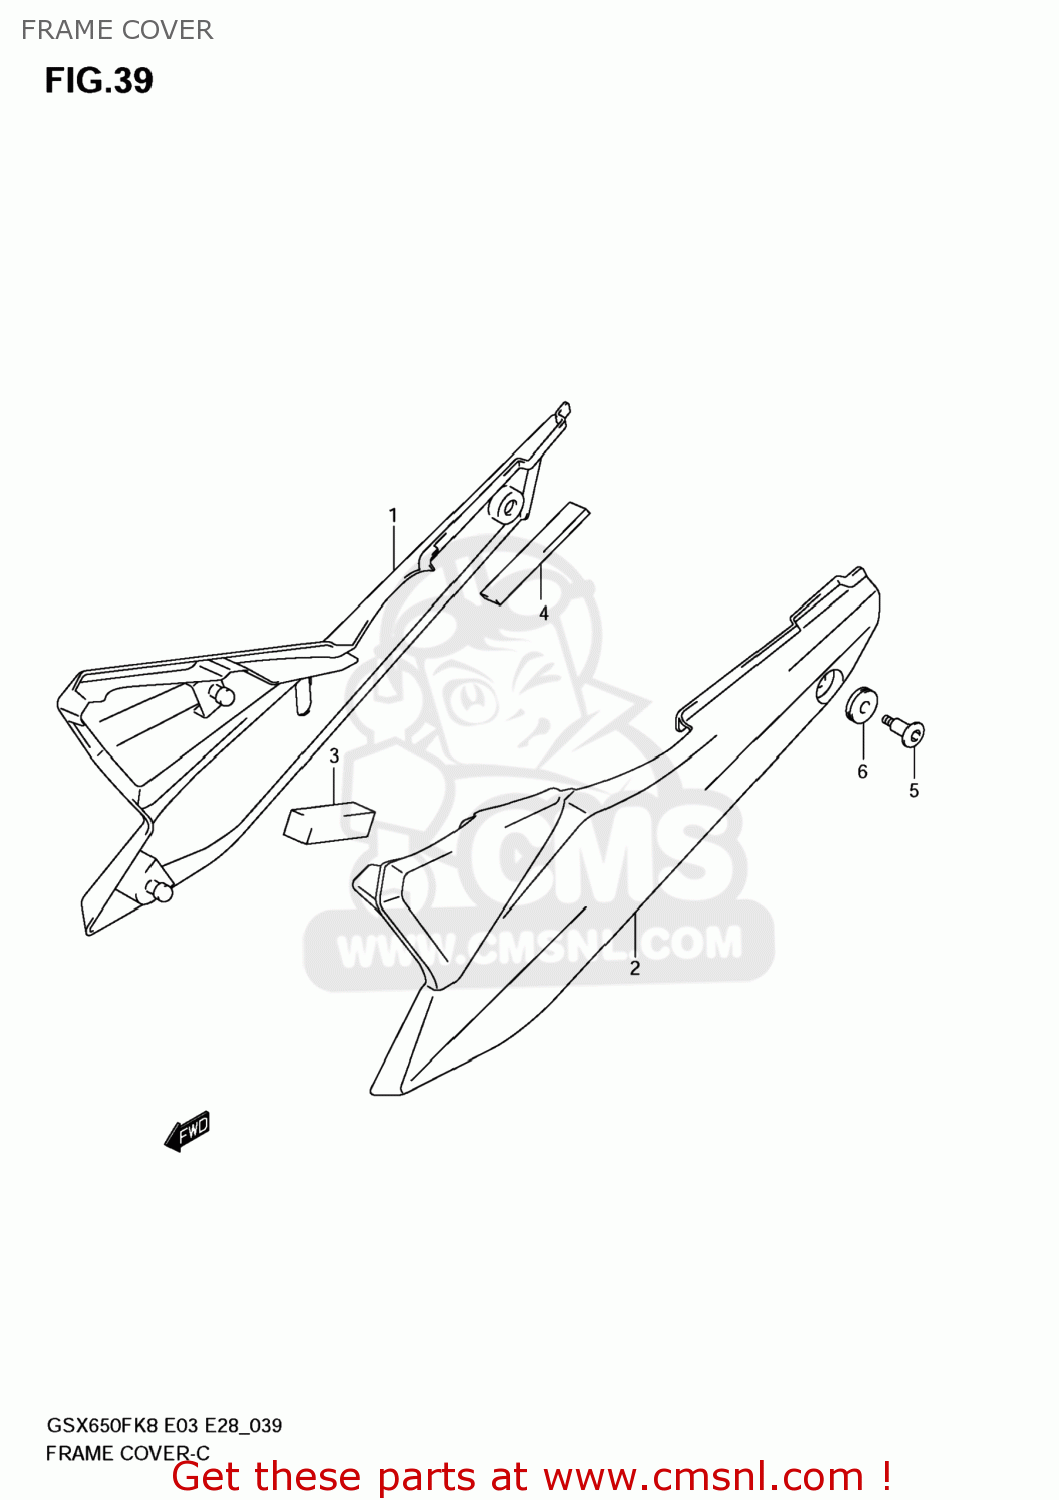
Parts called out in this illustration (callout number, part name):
1	COVER,FRAME,R(BLACK)
2	COVER,FRAME,L(BLACK)
3	RUBBER
4	CUSHION
5	SCREW,FUEL TAN
6	CUSHION
